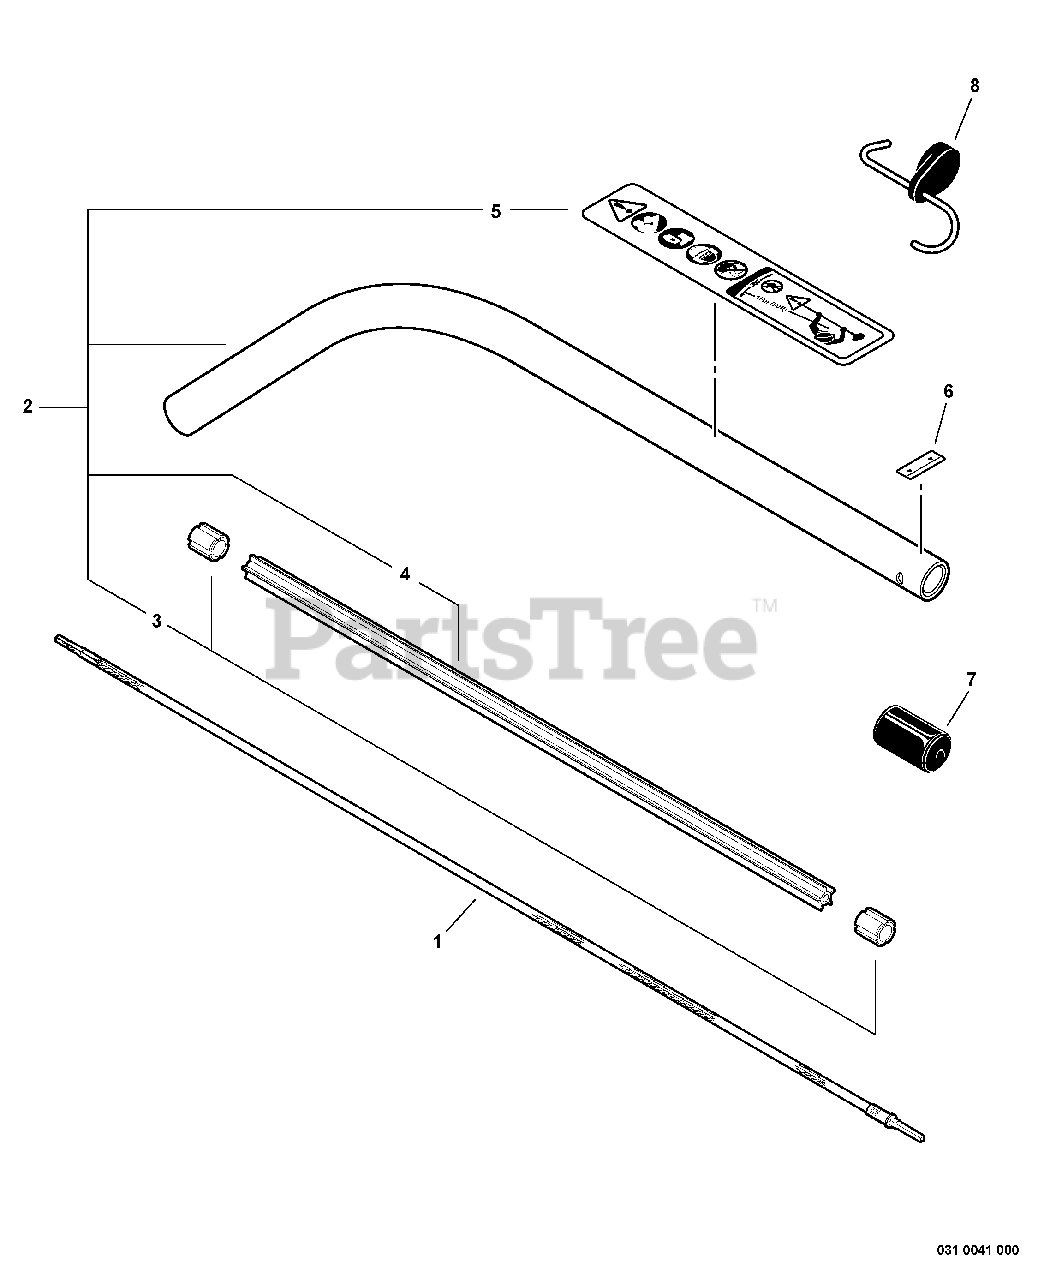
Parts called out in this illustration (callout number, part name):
1	DRIVESHAFT - FLEXIBLE
2	MAIN PIPE ASSY
4	LINER - FLEXIBLE
5	LABEL - CAUTION
6	LABEL - ALIGNMENT
8	PAS ATTACHMENT HANGER
